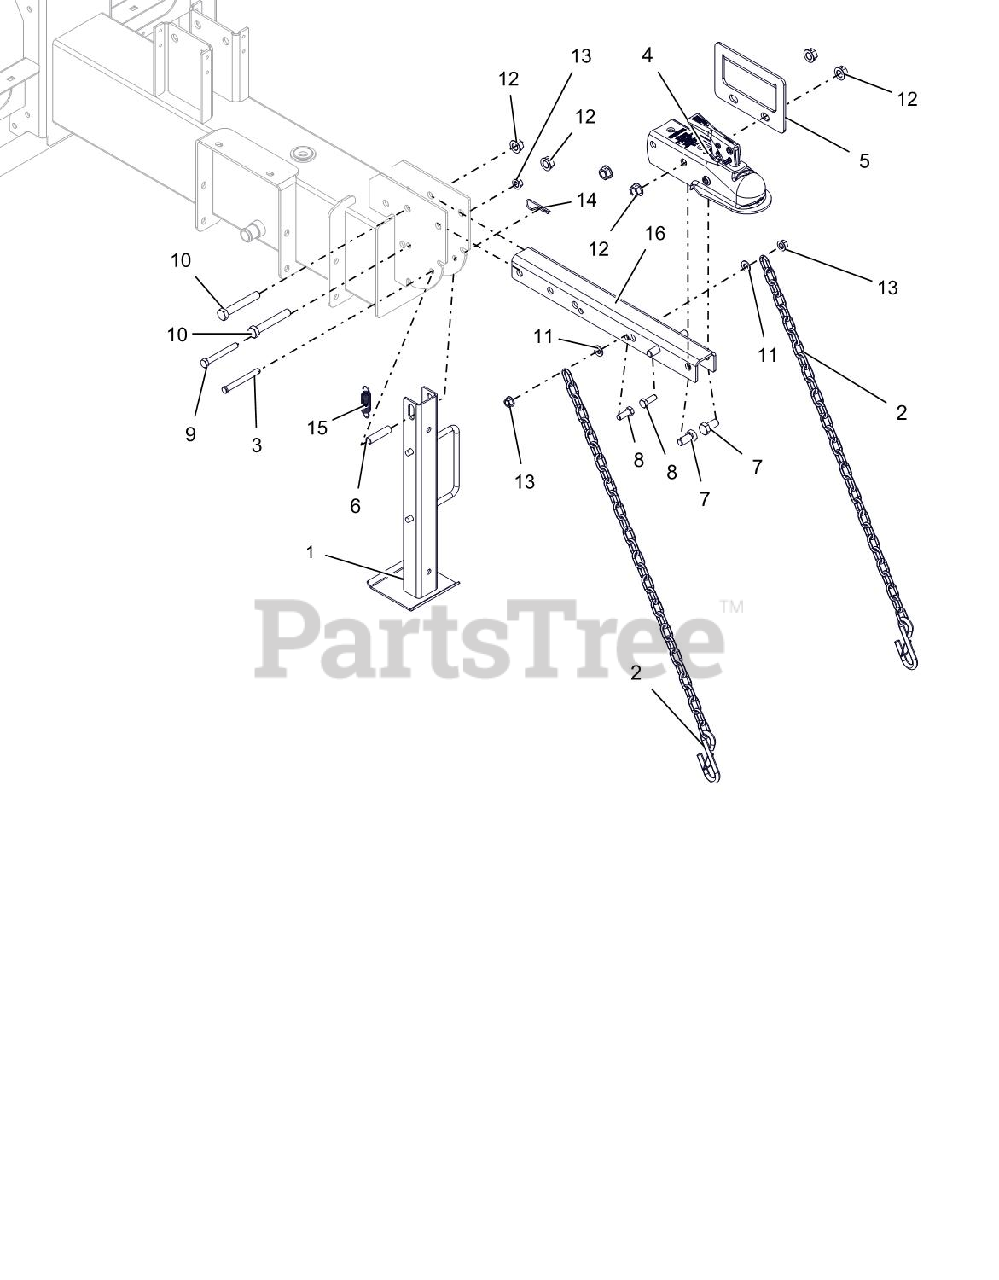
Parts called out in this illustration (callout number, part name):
1	WLDMT, JACK STAND
2	CHAIN, SAFETY 3/16"-30LINK
3	PIN-CLEV .371X3.25 YWZC
4	COUPLER-BALL 2.000"
5	HANDLE, SPLITTER DRAW BAR
6	SPCR, WHEEL .385X.500X2.00
7	@BLT-HEX .50-13X1.00 GR5 YWZC
8	@BLT-HEX .38-16X1.00 GR5 YWZC
9	@BLT-HEX .38-16X3.00 GR5 YWZC
10	@BLT-HEX .50-13X3.25 GR5 YWZC
11	@WSHR-FL-STL.406X.812X.065 YWZ
12	NUT-LK-CTR-FLG .50-13 YWZC
13	@NUT-LK-TOP-FLG .38-16 YWZC
14	HAIRPIN, #7 CLIP .094X2.31 YWZ
15	SPRG, TENSION .063X.625X2.50
16	HITCH BAR W/SAFETY DECAL
